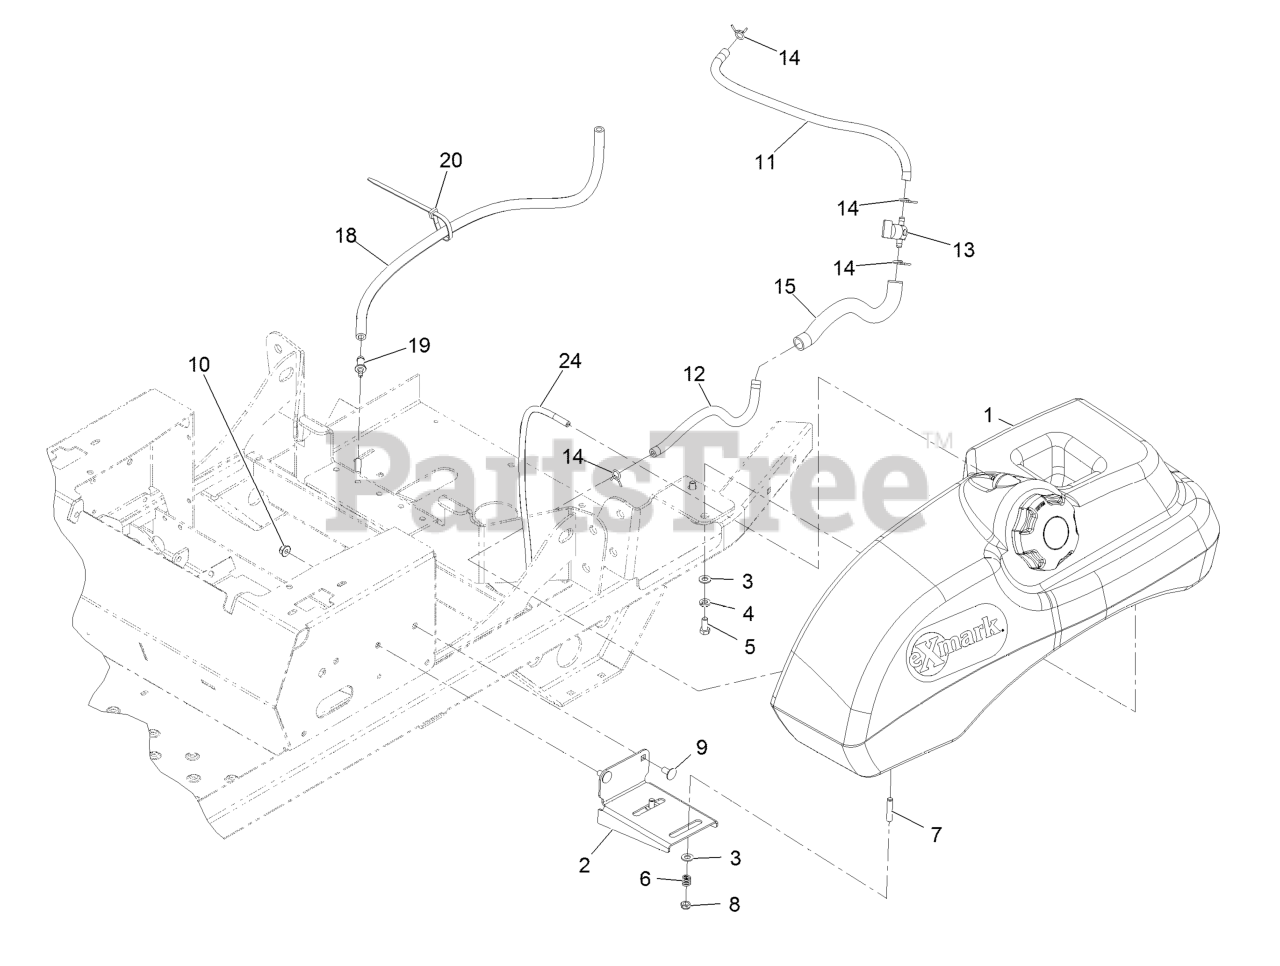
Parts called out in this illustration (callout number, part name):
1	ASM-FUEL TANK
2	BRACKET-TANK AND FENDER
3	WASHER-PLAIN
4	WASHER-LOCK
5	SCREW-HH
6	SPRING-TANK, FUEL
7	STUD
8	NUT-LOCK, NI
9	SCREW-CARR
10	NUT-HF, NI
11	HOSE-FUEL
12	HOSE-FUEL
13	VALVE-FUEL
15	CONDUIT-FUEL LINE
18	HOSE-FUEL
19	FITTING-ORIFICE, STRAIGHT
20	TIE-PLASTIC
24	HOSE,EMISSIONS
